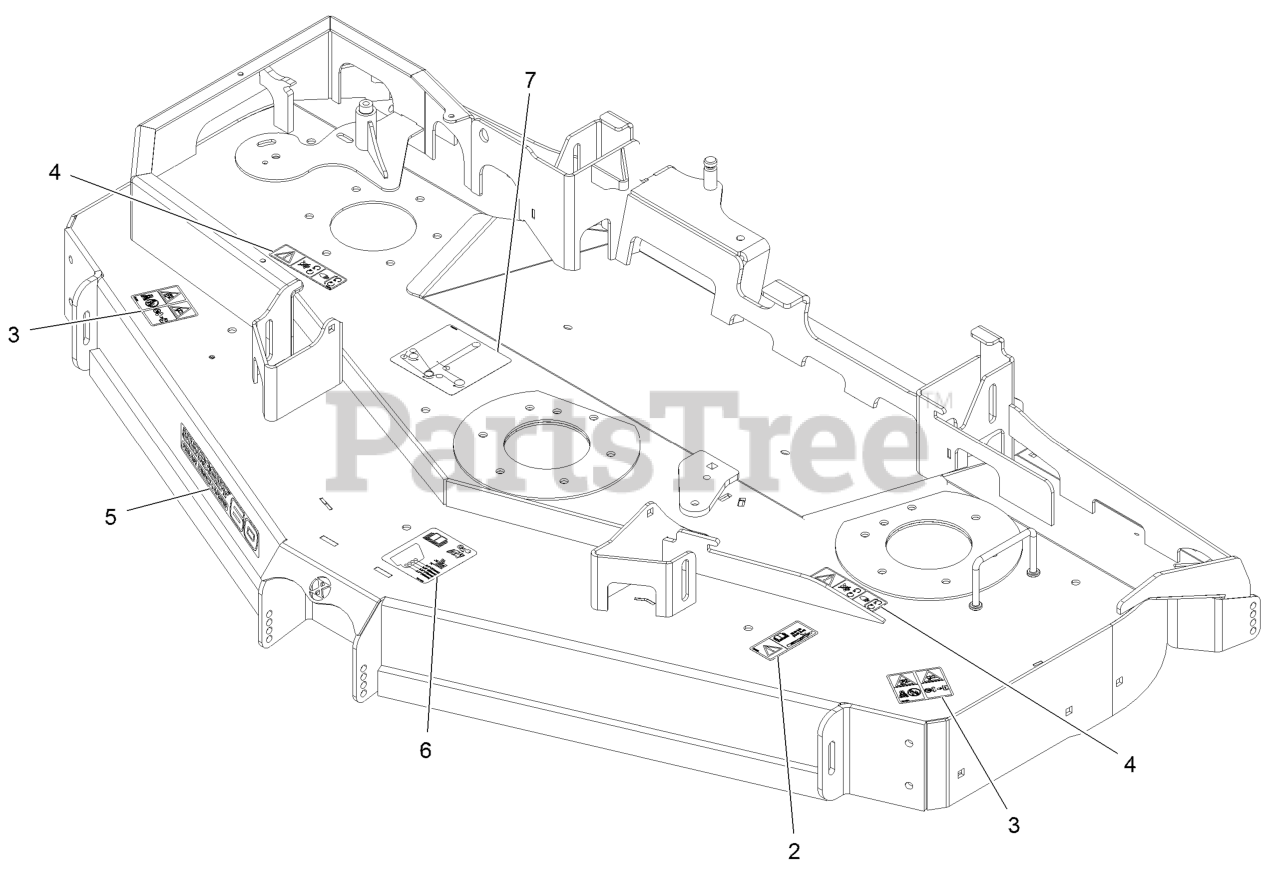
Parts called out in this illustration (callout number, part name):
2	DECAL-BOLT TORQUE
4	DECAL-COVER, MISSING
5	Decal, 60Rd
6	DECAL-ROLLER, ANTI-SCALP
7	DECAL-ROUTING, BELT
